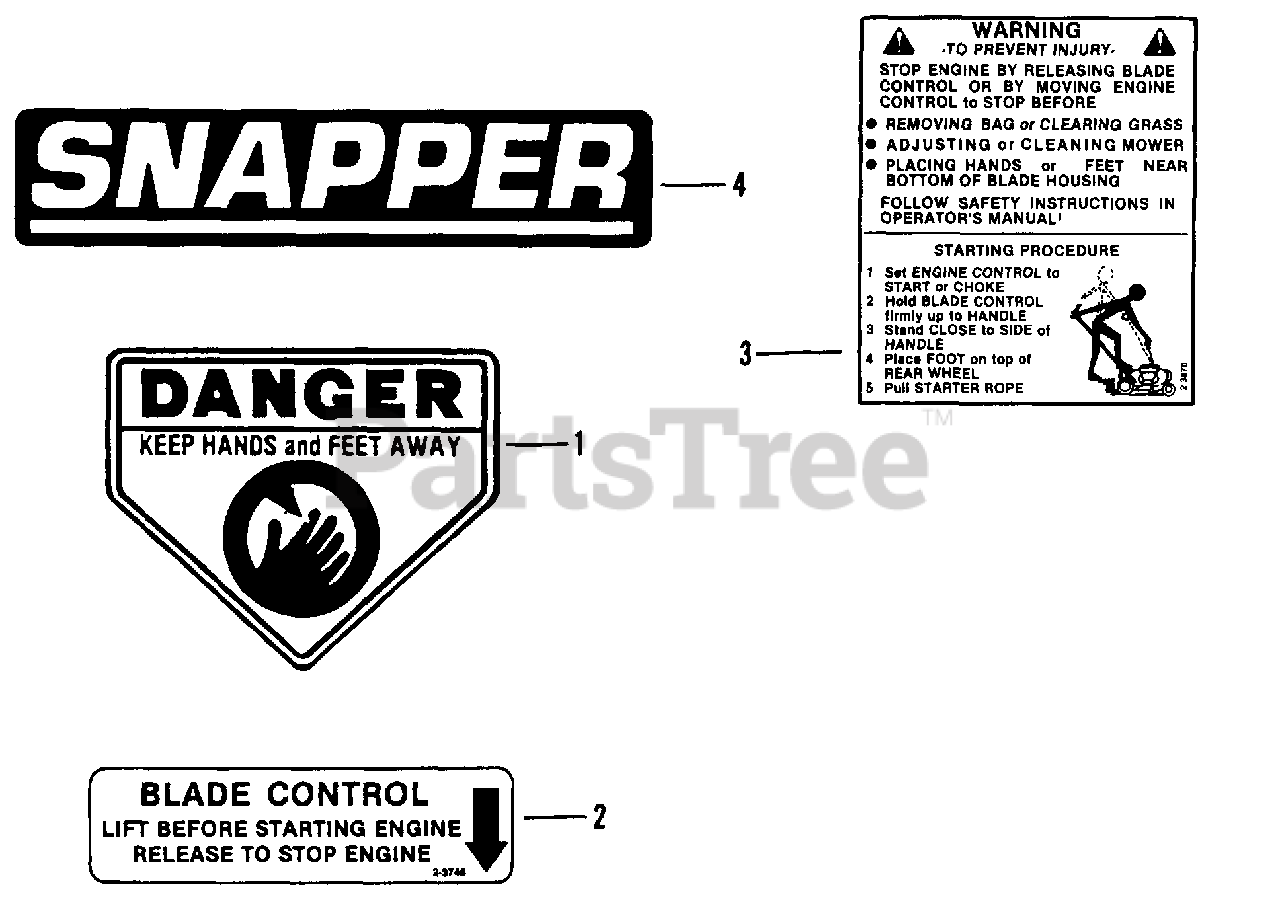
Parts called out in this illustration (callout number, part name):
1	DECAL, Danger
2	DECAL, Blade Control
3	DECAL, Warning
4	DECAL, SNAPPER
